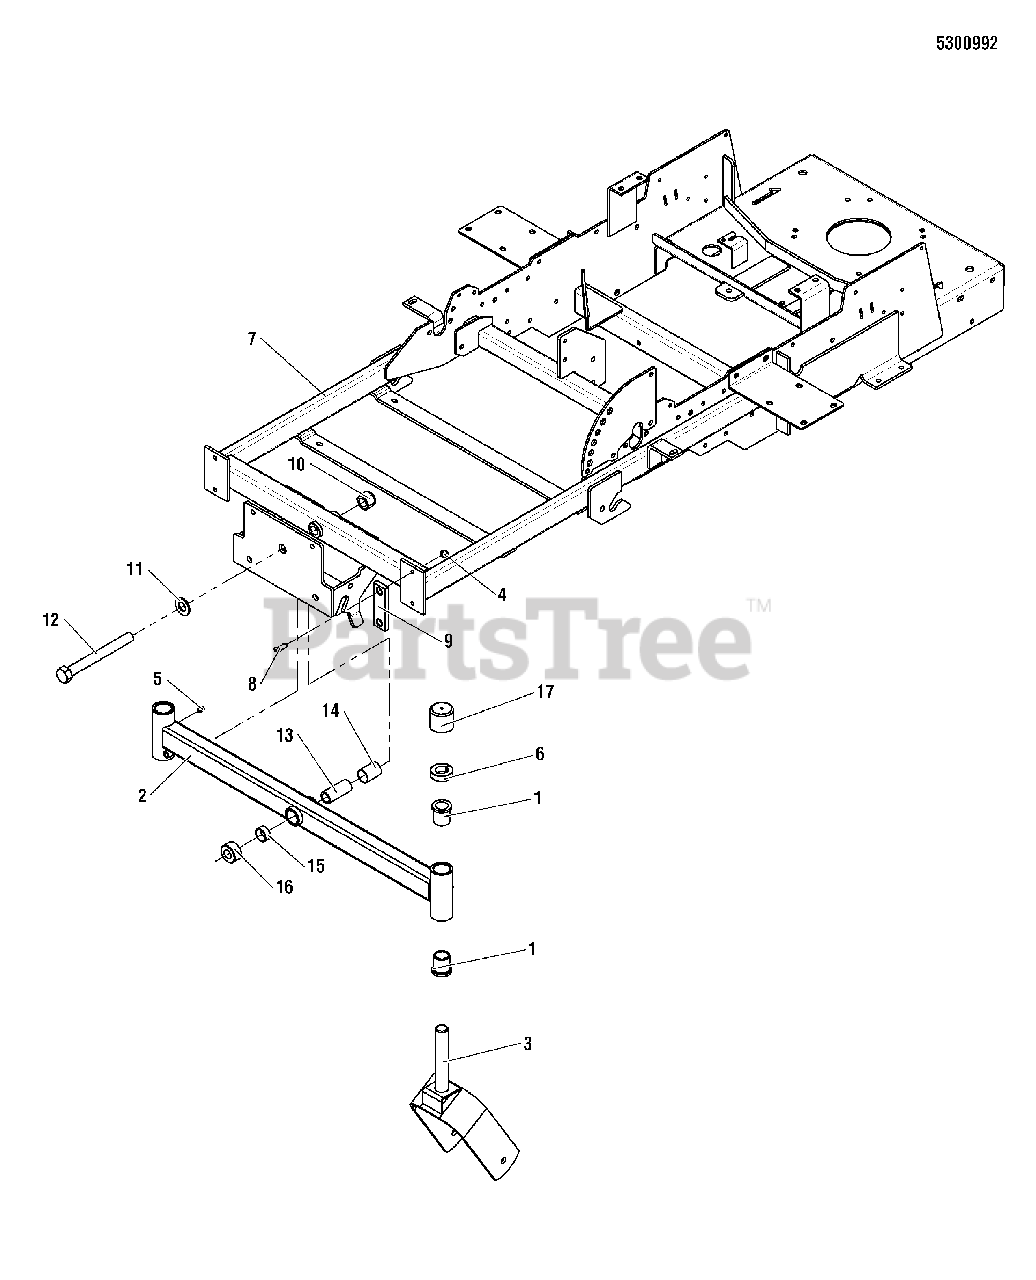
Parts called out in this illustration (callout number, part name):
1	BUSHING, FLANGE
2	WELD, PIVOTING FRONT END - RED
3	WELD, CASTER YOKE - RED
4	NUT, 5/16-18 HEX NYLON LOCK
5	GREASE FITTING, 1/4-28 STRAIGHT
6	COLLAR, 1" SPLIT
7	WELD, MAINFRAME, SNAPPER ZT, RED
8	SCREW, 5/16-18 X 1, PHILLIPS HD, BZ
9	PAD, FRICTION, .375 X 1.25 X 4.00
10	NUT, 3/4-16 HEX NYLON LOCK
11	WASHER, 3/4 SAE
12	BOLT, 3/4-16 X 7" YZ GD5
13	SPACER, .75 X 1.00 X 2.38
14	PIVOT BEARING, 1.00" X 1.125" OD X 1.50"
15	PIVOT BEARING, 1.00 X 1.125 OD X .50
16	SPACER, .76X 1.50 X .79
17	CAP, VINYL 1.687 X 1-1/2
